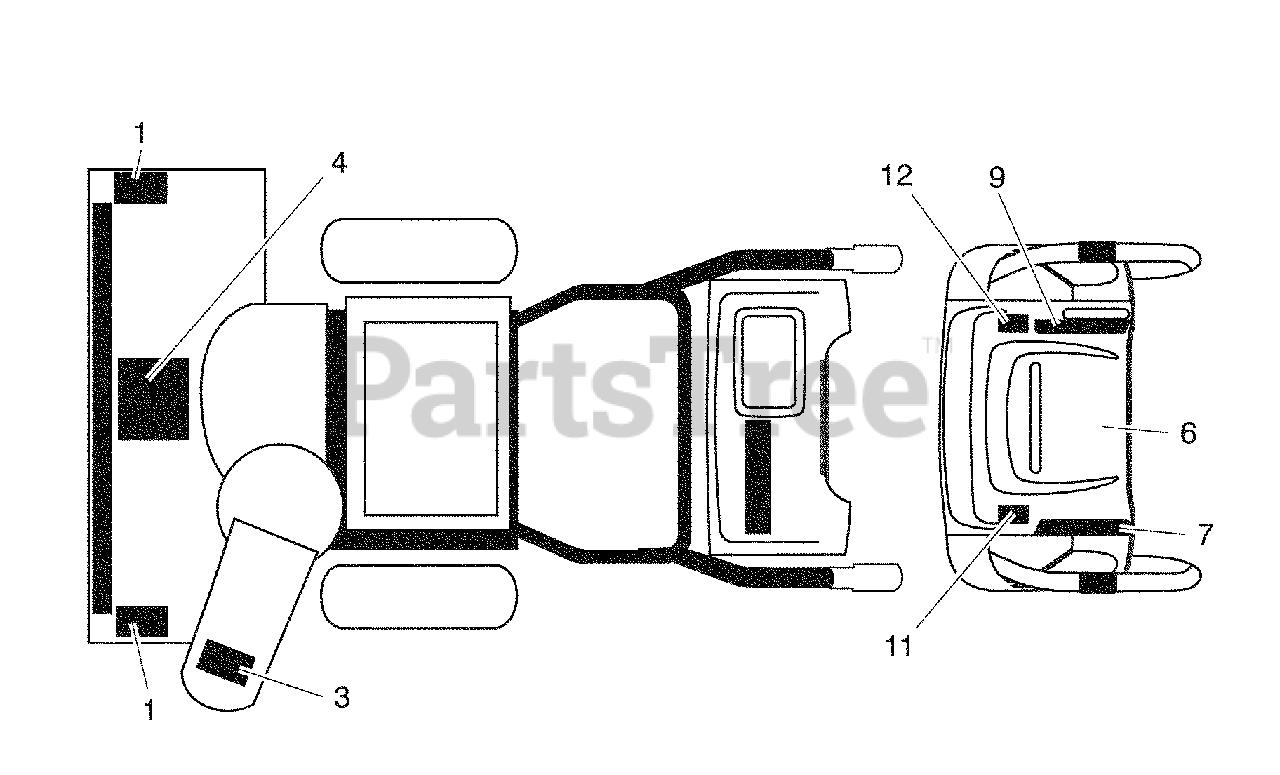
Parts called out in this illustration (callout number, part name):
1	DECAL, DANGER
3	DECAL, DANGER, DEFLECTOR
4	DECAL, DANGER
6	DECAL, INSTRUCTION
7	DECAL, REMOTE DEFLECTOR
9	DECAL, SPEED CONTROL
11	DECAL, LH TRIGGER
12	DECAL, RH TRIGGER
